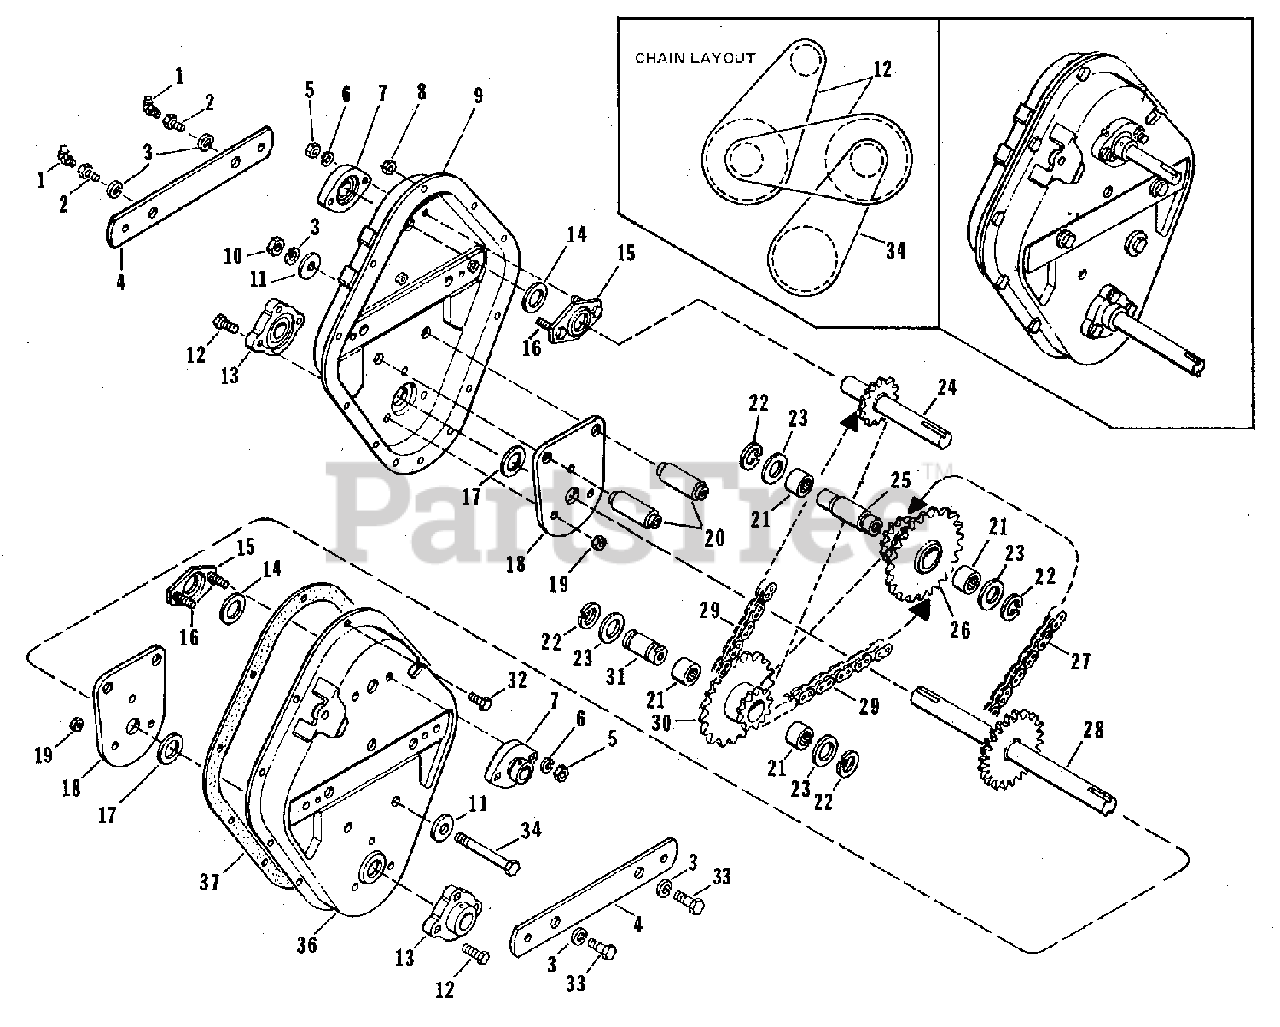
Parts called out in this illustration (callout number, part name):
1	FITTING, Grease
2	BOLT, R.H. Side
3	WASHER, Lock, 1/2
5	NUT, Full Hex, 5/16-18
6	WASHER, Lock, 5/16"
8	LOCKNUT, Full Hex, 5/16-18
9	HALF CASE ASSEMBLY, R.H.
10	NUT, Full Hex, 1/2-13
11	WASHER, Flat, 1/2
12	SCREW, Thread Forming, 3/8-16 x 1-1/2
15	UPPER BEARING PLATE ASSEMBLY
16	SCREW, Hex Cap, 5/16-18 x 1-1/2
18	PLATE, Reinforcing
19	NUT, Hex Lock, Jam 3/8-16
21	BEARING, Roller
22	RING, Retaining
24	PULLEY SHAFT ASSEMBLY
25	SPACER, Intermediate
26	SPROCKET ASSEMBLY
28	TINE SHAFT ASSEMBLY
30	SPROCKET ASSEMBLY
31	SPACER, Intermediate
32	SCREW, Hex Cap, 5/16-18 x 5/8
33	SCREW, Hex Cap, (L.H.) 1/2-20 X 1-1/4
34	SCREW, Hex Cap, 1/2-13 x 4
35	HALF CASE ASSEMBLY, L.H.
